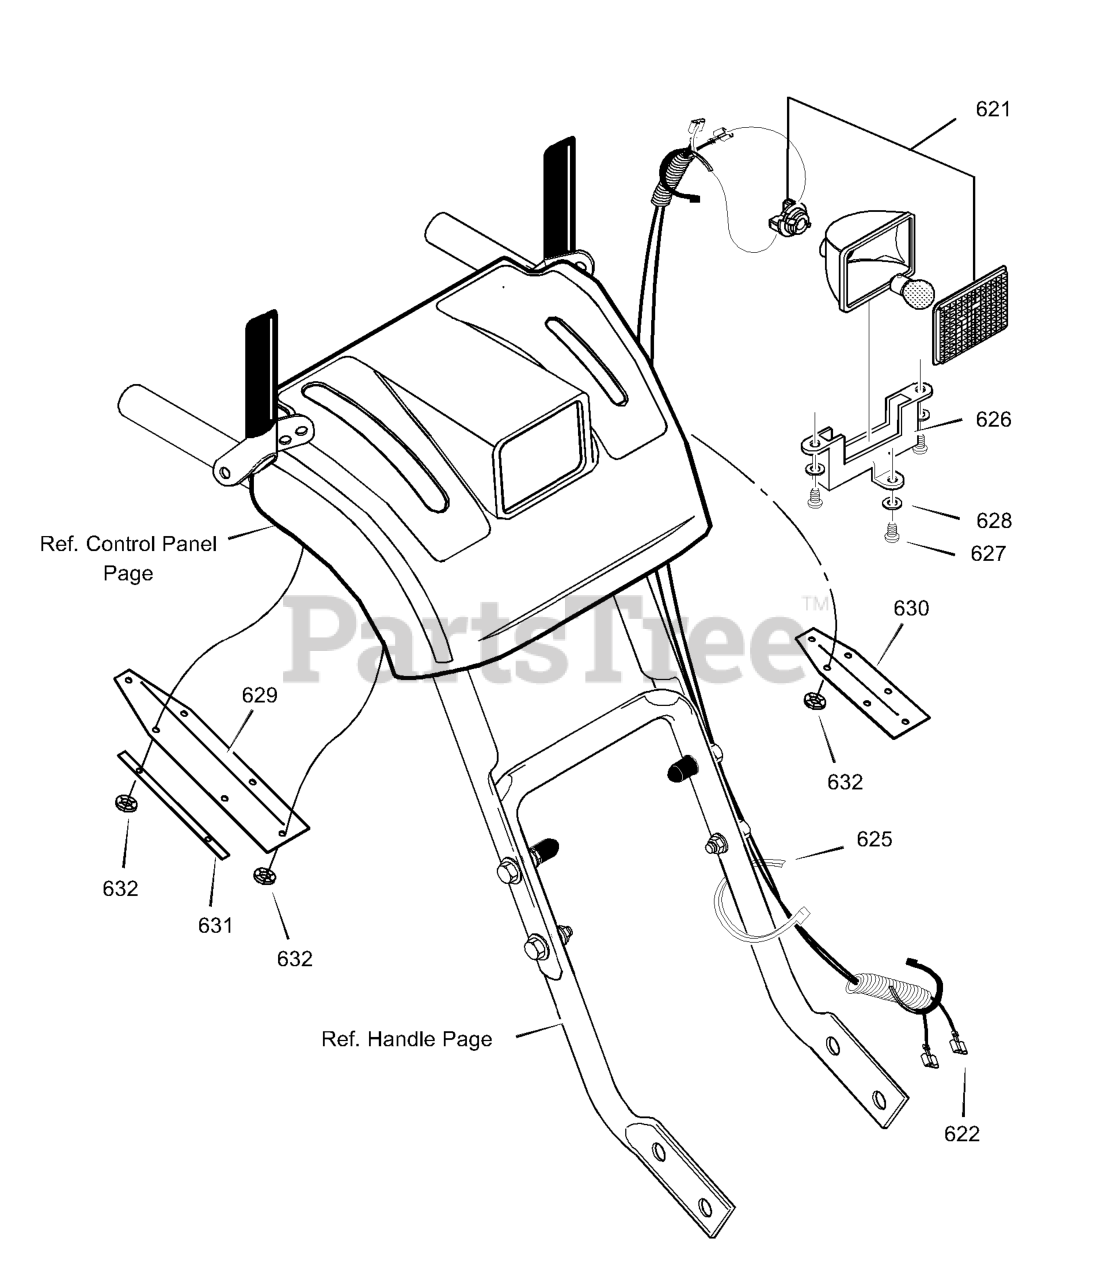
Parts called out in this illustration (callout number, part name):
621	LIGHT, HALOGEN
622	HARNESS, WIRE
625	TIE, CABLE
626	BRACKET, LIGHT
627	SCREW #8 X .50
628	WASHER, FLAT
632	NUT, PUSH
